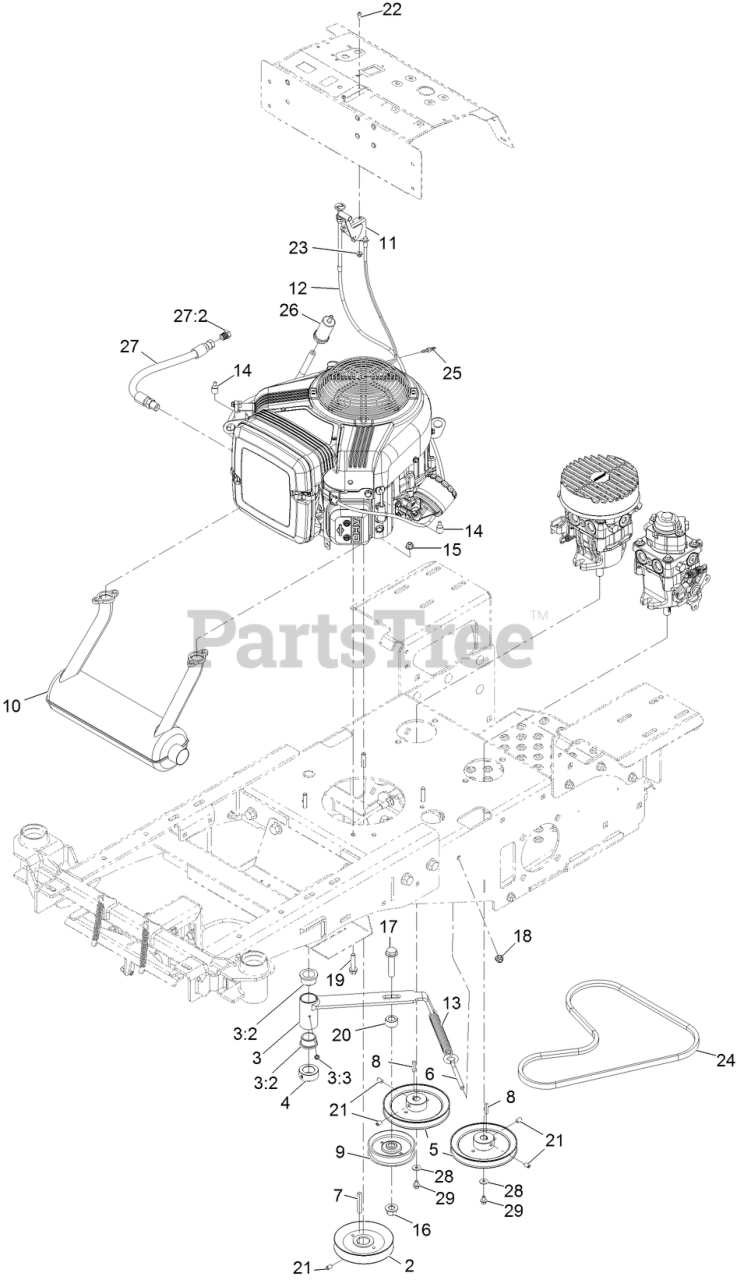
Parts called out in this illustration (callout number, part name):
2	PULLEY-DRIVE
3	ASM, ARM-TENSION
3:2	BUSHING-FLANGE
3:3	FITTING-GREASE, ZERK
4	COLLAR
5	PULLEY ASM
6	BOLT, EYE - 5/8 X 5/16-18 X 5
9	PULLEY-IDLER, FLAT
10	BRIGGS 16/18 HP MUFFLER
11	CABLE-THROTTLE
12	CABLE-CHOKE
13	SPRING-EXTENSION
14	TUBE-SHRINK, HEAT
15	NUT-HEX FLANGE
16	NUT-LOCK
17	SCREW-HHF
18	NUT-HF, NI
19	SCREW-HHF
20	SPACER
21	SETSCREW-HSH
22	SCREW-HSBH
23	NUT-HEX FLANGE
24	BELT-V, A48
25	FITTING-STR
26	FILTER-FUEL
27	OIL DRAIN HOSE ASM (W/PLUG)
28	WASHER
29	SCREW-HHF
